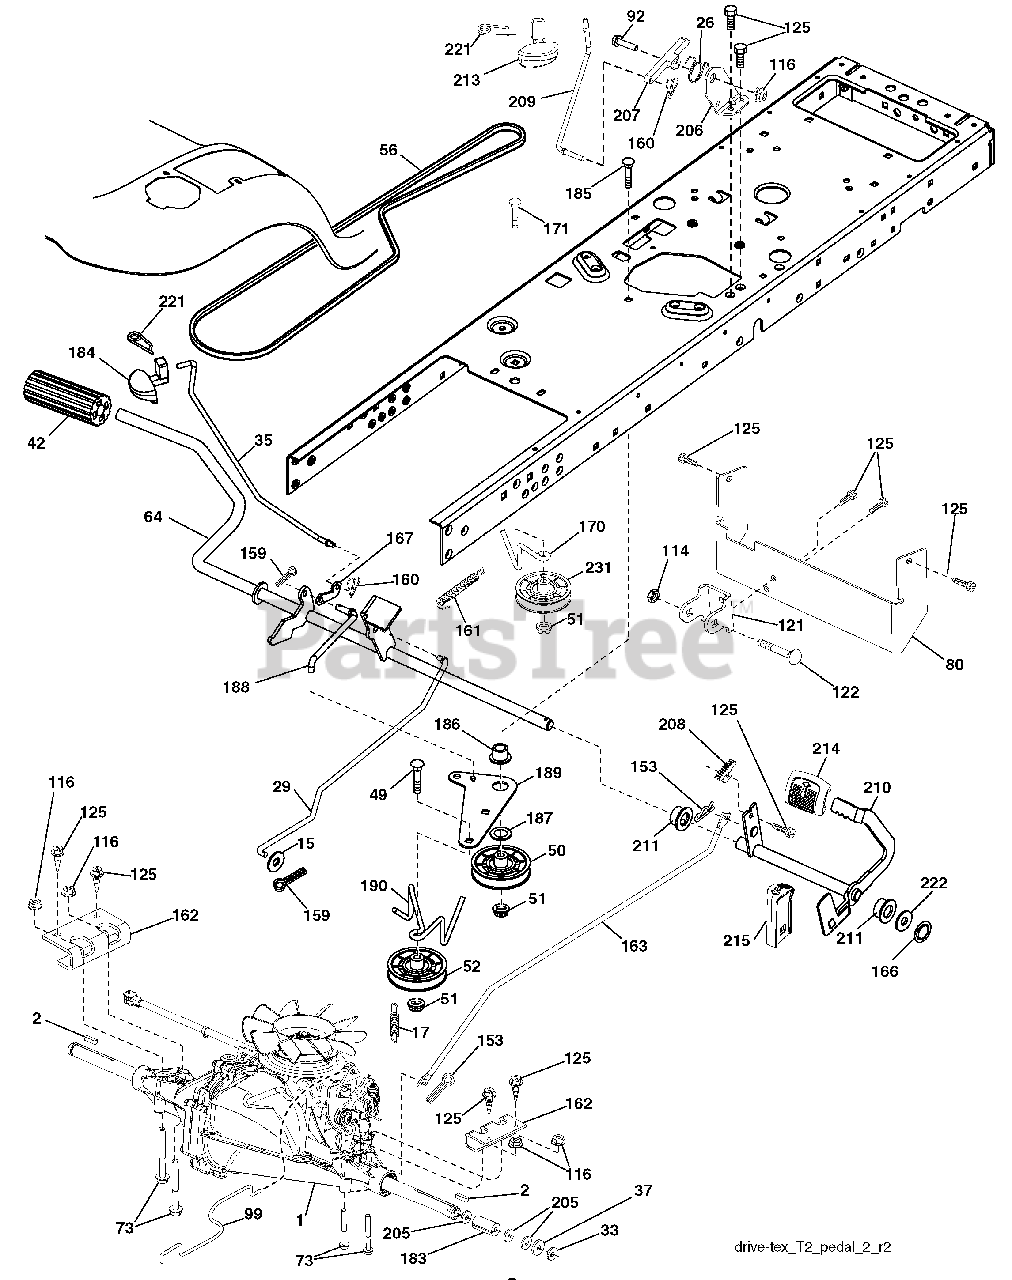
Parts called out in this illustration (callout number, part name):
1	Transaxle, Hydro T2
2	Key
15	Washer 13/32 x 13/16 x 16 Ga.
17	Spring, Brake
26	Spring Return Cruise
29	Rod, Brake
33	Ring E
35	Rod, Brake, Park
37	Washer 25/32 x 1-1/4 x 16 Ga.
42	Cover, Foot Pedal
49	Bolt
50	Pulley Idler Flat
51	Lock Nut 3/8-16
52	Idler V-Groove 910" Offset
56	V-Belt, Drive
64	Shaft Asm. Pedal Brake Control
73	Bolt 5/16-18 Gr. 5
80	Strap Torque
92	Bolt Fin Hex 5/16-18 unc x 1.25
99	Rod Asm Bypass Spring
114	Nut Lock 5/16-18 unc
116	Nut Lock Hex Flange 5/16-18
121	Bracket Strap Torque
122	Bolt 5/16-18 x 2.50
125	Screw 5/16-18 x 3/4
153	Retainer Spring
159	Pin Cotter 1/8 x 3/4
160	Retainer Clip
161	Spring, Return, Clutch
162	Adapter Transaxle
163	Rod Pedal Control
166	Nut Push .625
167	Latch Brake Parking
170	Keeper Belt Centerspan
171	Bolt
183	Spacer Axle
184	Handle Parking Brake
185	Bolt
186	Spacer Retainer
187	Washer
188	Link Clutch Ground Drive
189	Bellcrank Ground Drive
190	Keeper Bellcrank Ground Drive
205	Washer 25/32 x 1-5/8 x 16 Ga.
206	Bracket Mount Latch Cruise
207	Latch Control Cruise
208	Gear Sector Control Cruise
209	Rod Control Cruise
210	Rockr Asm. Pdeal Control
211	Bearing Nylon
213	Knob control Cruise
214	Pad Pedal Forward
215	Pad Pedal Reverse
221	Retainer Spring Clip Handle
222	Washer 21/32 x 1-1/4 10 Ga.
231	Idler V-Groove 1.688
